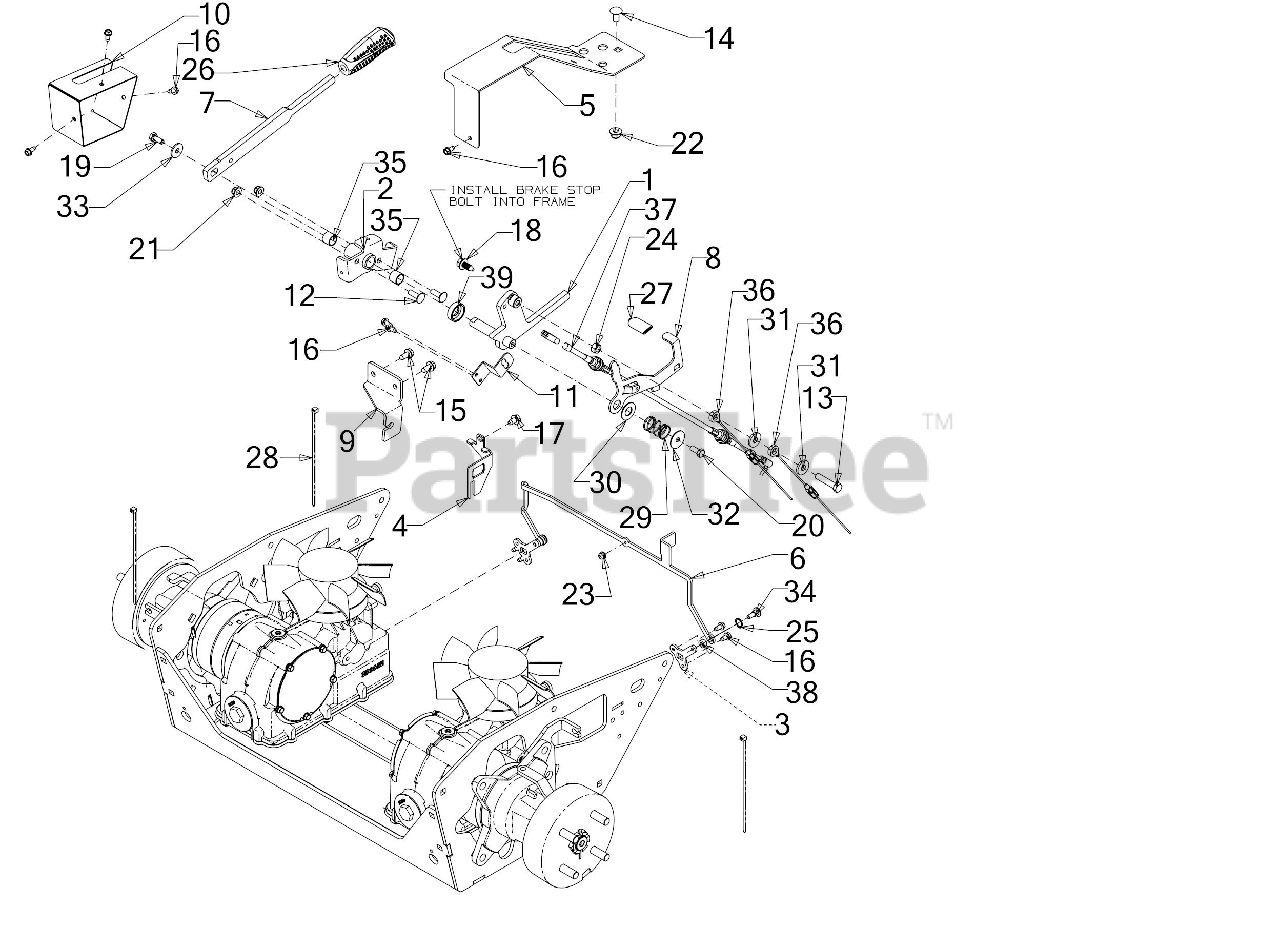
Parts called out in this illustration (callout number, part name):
1	PIVOT BRAKE SHAFT ASSEMBLY
2	PIVOT TUBE ASSEMBLY
3	TRANSMISSION BYPASS LEVER
4	NEUTRAL BRACKET
6	DUMP VALVE ACCTUATOR BRACKET
7	PARKING BRAKE LEVER
8	DUMP VALVE RELEASE LEVER
9	LOWER CABLE MOUNTING BRACKET
10	BRAKE LEVER PIVOT COVER
11	3-POLE SWITCH BRACKET
12	CARRIAGE BOLT 5/16-18 x 1.00
13	HEX SCREW 3/8-16 x 1.75 GR5
14	CARRIAGE BOLT 3/8-16 x .750 GR5
15	SCREW 5/16-18 x .750
16	SCREW 1/4-20 X.500
17	SCREW 5/16-18 x .500
18	HEX SCREW WASH TT 3/8-16 x .875
19	SCREW 5/16-18 x .750
20	SCREW 5/16-18 x .75 GR5
21	FLANGE LOCK NUT 5/16-18
24	HEX NUT
25	SNAP RING
27	SEAT ADJUSTER GRIP
28	7" CABLE TIE
29	COMPRESSION SPRING .844X.970X1.50
30	FLAT WASHER .640ID X1.24OD x .06
31	FLAT WASHER .385 x 1.00 x .135
32	FLAT WASHER .322 ID x 1.25 x .060
33	FLAT WASHER 1.0 OD:.331 ID
34	SHOULDER SCREW .375X.280:1/4-14
35	SLEEVE BEARING
36	BRAKE CABLE
37	NEUTRAL CONTROL CABLE
